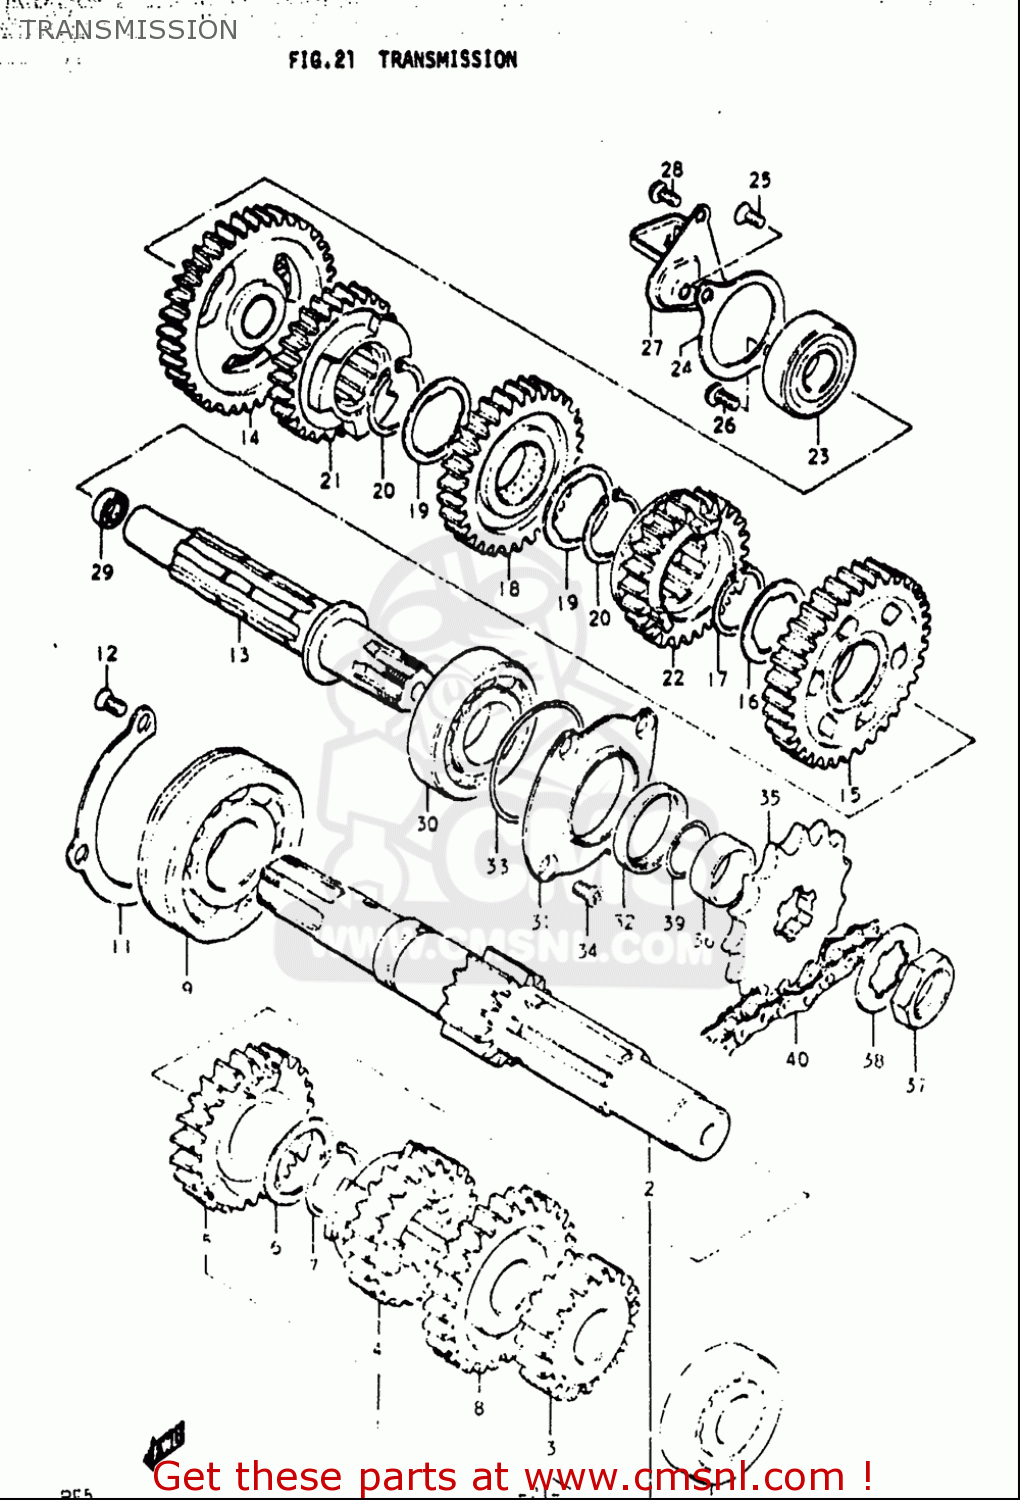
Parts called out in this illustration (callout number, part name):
6	WASHER,LOCK
7	CIRCLIP
10	BEARING(20X52X15)
12	SCREW
16	WASHER,LOCK
17	CIRCLIP
19	WASHER,LOCK
20	CIRCLIP
23	BEARING(20X47X14)
24	PLATE,COUNTERSHAFT BEARING
25	SCREW
26	SCREW
28	SCREW
29	SEAL,OIL(8X14X4)
30	BEARING(25X62X17)
32	SEAL,OIL(32X42X6)
33	O RING(D:1.9,ID:63.1)
34	SCREW
37	NUT
38	WASHER,LOCK
39	O RING(D:1,ID:24.5)
40	CHAIN,DRIVE(DID630YL,96LE)
